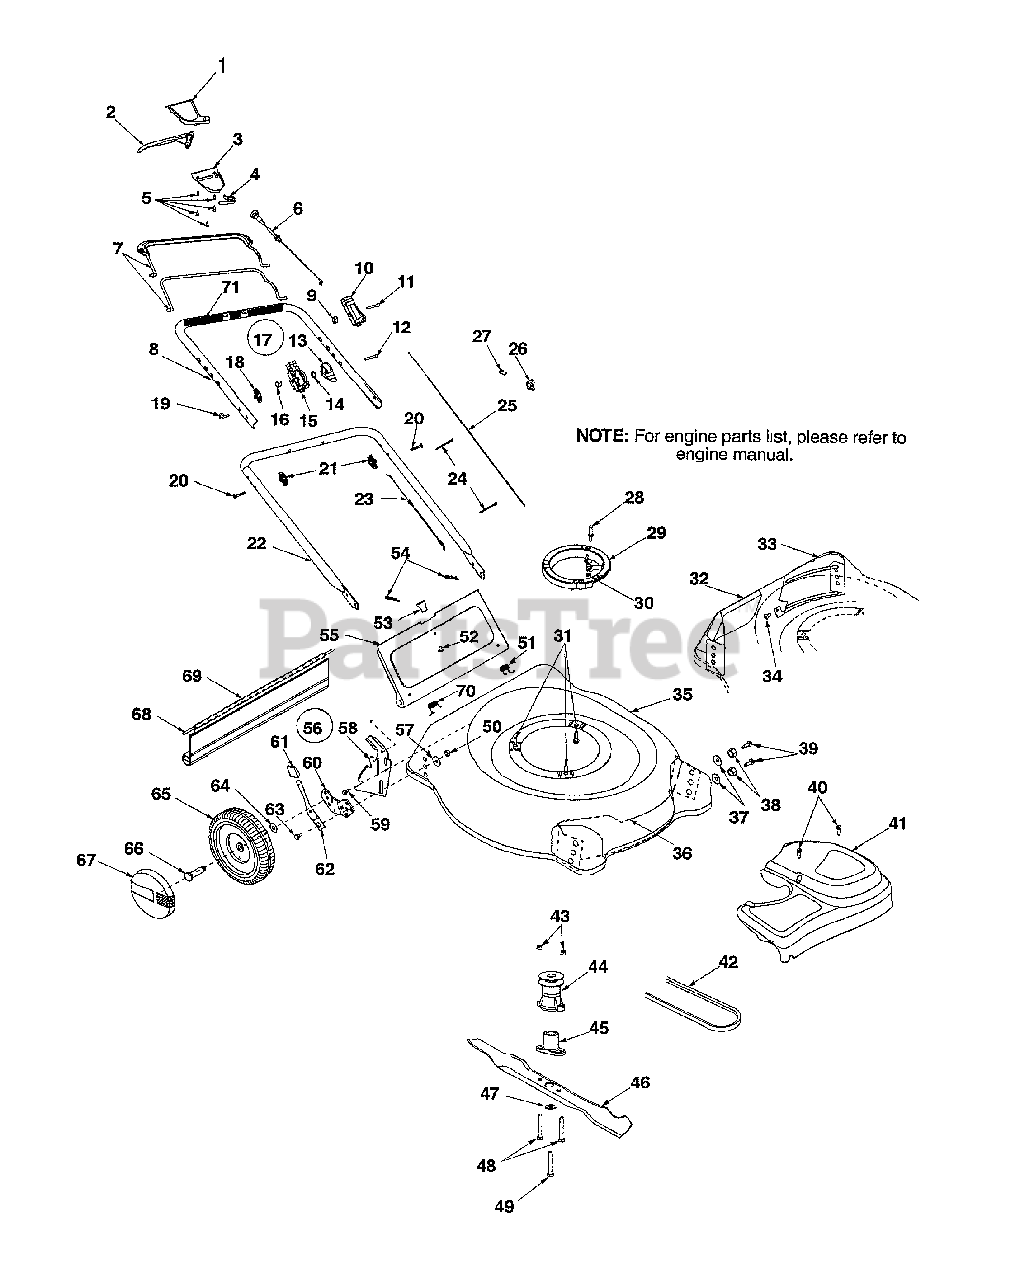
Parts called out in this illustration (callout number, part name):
1	Upper Drive Cover
2	Drive Lever
3	Lower Drive Cover
4	Mounting Cap
5	Screw #10-12:75
6	Drive Cable
10	Control Housing
11	Oval C-Sunk Scr. 1/4-20 x 1.31
12	Oval C-Sunk Scr. 1/4-20 x 1.81
13	Throttle Lever
14	Curved Washer .663 x .980 x .014
15	Throttle Housing
16	Hex Lock Nut 1/4-20 Thd.
17	Throttle Body Comp.
19	Eye Bolt 1/4-20
20	Carriage Bolt 5/16-18 x 2.0
23	Throttle Cable: 55" (B&S)
24	Tie Cable
25	Control Cable 43" (B&S)
26	Cable Clamp (B&S)
27	Hex Screw: T: #10-32 (B&S)
28	Pin-Belt Keeper
29	Engine Spacer
30	Hex Nut 1/4-20 Thread
31	Tapp Screw w/Hex Lock Wash
34	Scr. AB: 1/4-14 .625 Trust
38	Bell Washer .39 x 1.13 x .062
39	Hex Screw 3/8-16 x .75
40	Screw #12 x .457
41	Front Drive Cover - Black
42	V-Belt
43	Hex Lock Nut 1/4-20
44	Drive Pulley
45	Blade Adapter
46	21" Mulching Blade w/star
47	Bell Washer .396 I.D. x 1.140 O.D. x
48	Hex Screw 1/4-2 0x 1.50
49	Hex Screw 3/8-24 x 2.50
50	Hex Nut 3/8-16
51	Torsion Spring L.H.
52	Scr. Tr. Mach #10-24 x .380
54	Cotter Pin
57	Bell Washer .39 ID x 1.38 OD
58	Handle Brkt Ass'y - LH
59	Hex Screw w/wsh. 1/4-14 x .62
60	Pivot Bar - LH
61	Knob
62	Spring Lever
63	Shldr Screw .500 Dia x .434 Long
64	Bell Washer .380 x .880 x .062
65	Wheel 8 x 1.75 Disk Bar Grey
66	Shldr Screw .498 x 1.445
67	Hubcap: Euro Grey 3 1/2"
68	Wire
69	Rear Flap
70	Torsion Spring R.H.
71	Foam Grip
